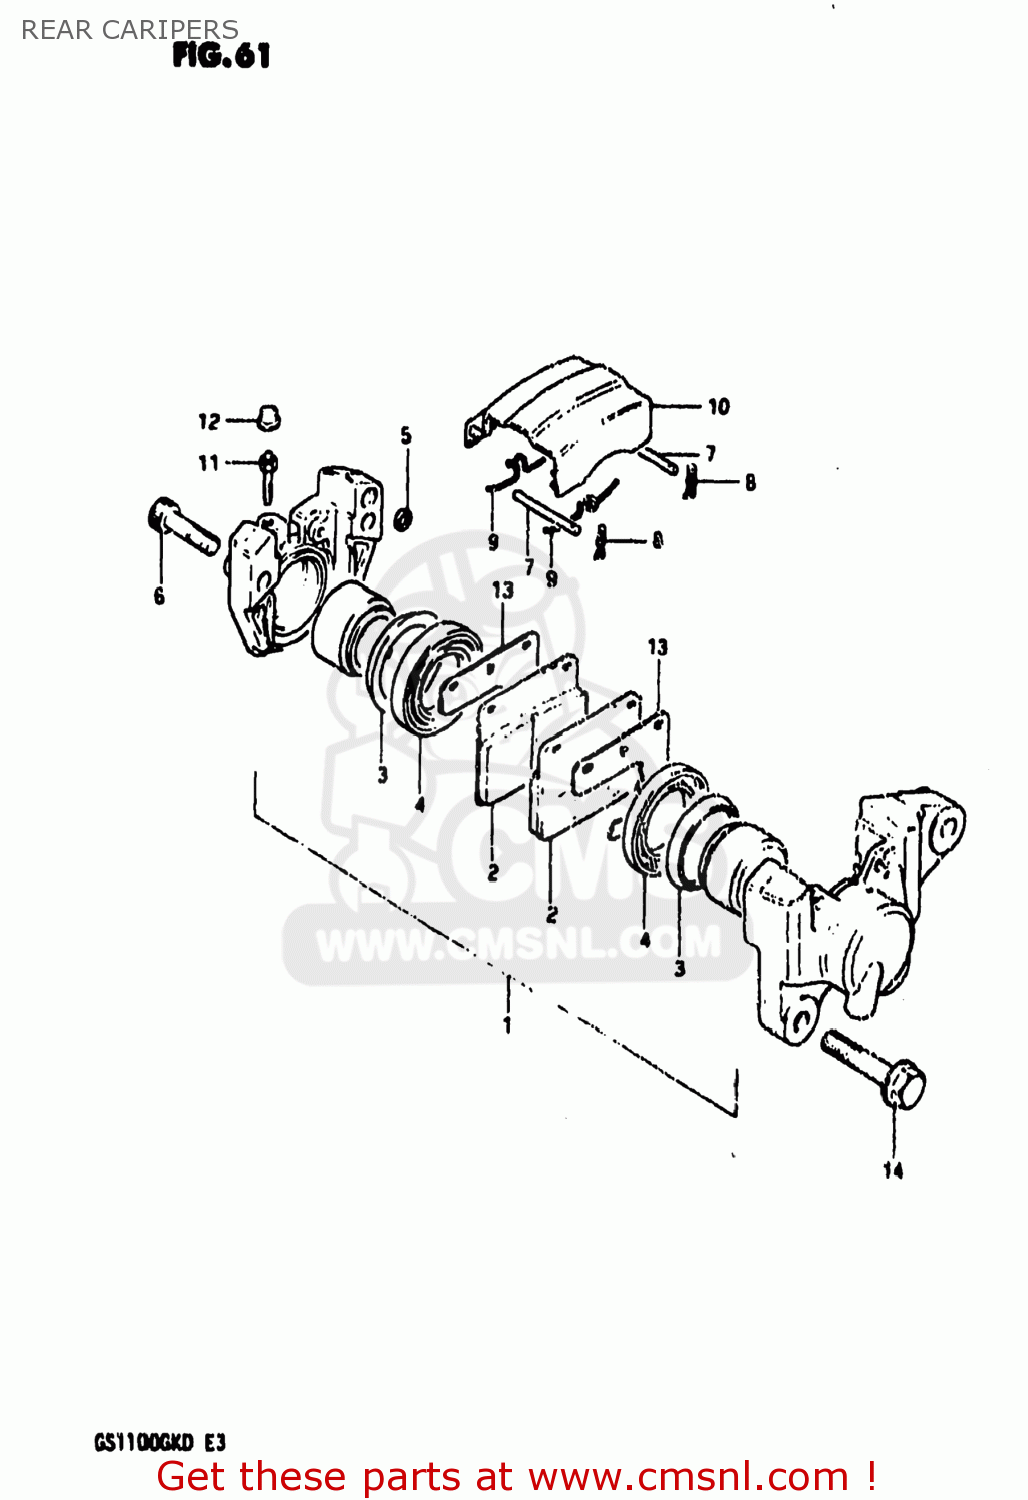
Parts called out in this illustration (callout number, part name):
1	PISTON/PAD SET
2	PAD,BRAKE (MCA)
3	SEAL,FR CALIPE
4	BOOT,PISTON
5	SEAL,JOINT
6	BOLT,CALIPER HOUSING
7	PIN,PAD
8	CLIP,PAD PIN
9	SPRING
10	COVER,DUST
11	BLEEDER
12	CAP,BREATHER
13	SHIM,RR CALIPER
14	BOLT
